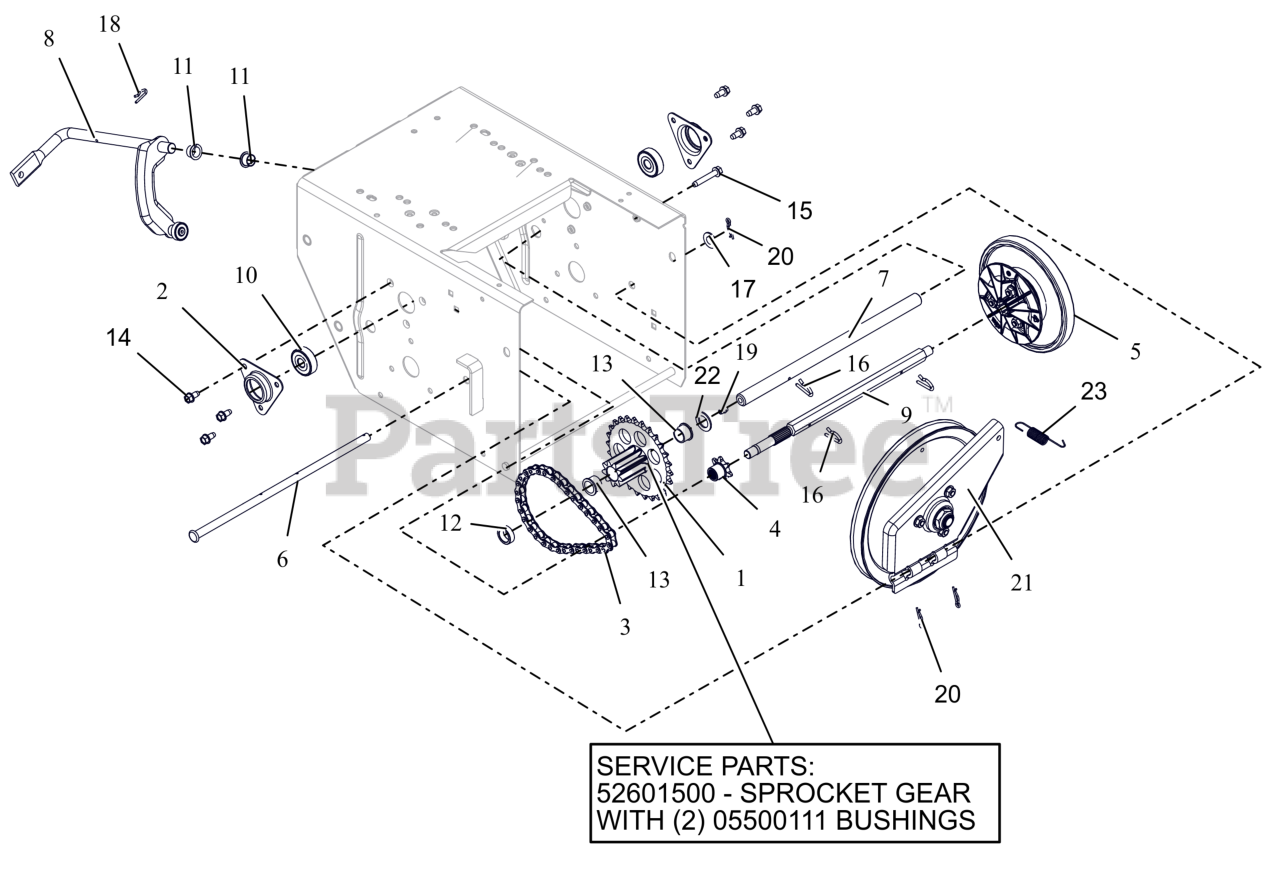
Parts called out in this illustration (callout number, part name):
1	PINION & SPROCKET
1	PINION & SPROCKET W/BUSHINGS
2	FLANGE, BEARING
3	CHAIN - #41, 32 PITCHES
4	SPROCKET, PINION 7T W/SPLINE
5	DISC, FRICTION DRIVE-ASSEMBLY
6	PIN, PIVOT
7	SHAFT, PINION
8	ARM, SHIFT - ASSEMBLY
9	SHAFT, HEX
10	BRG-BALL .437X1.375X.437
11	BUSHING, POLYLINER-.50 SPLIT
12	BSHG-SLV, .635X.880X.305
13	BSHG-FLG .625X.750X.500X.875
14	SCR-TAP .25-20X.50 HWH ZCC
15	SCR,TAP .25-20X1.50 HWH TR ZCC
16	PIN, SPRING CLIP
17	WSHR,FLT .406X.812X.065 ZCC
18	CLIP, SPRING
19	ZERK,FITTING .25X.125 DRIVE IN
20	PIN, HAIR #225 .072X1.09
21	PLATE, SWING ASSEMBLY-DEEP
22	WSHR, FLT .630X1.005X.062 ZCC
23	SG-TENS .048X.50X2.8
